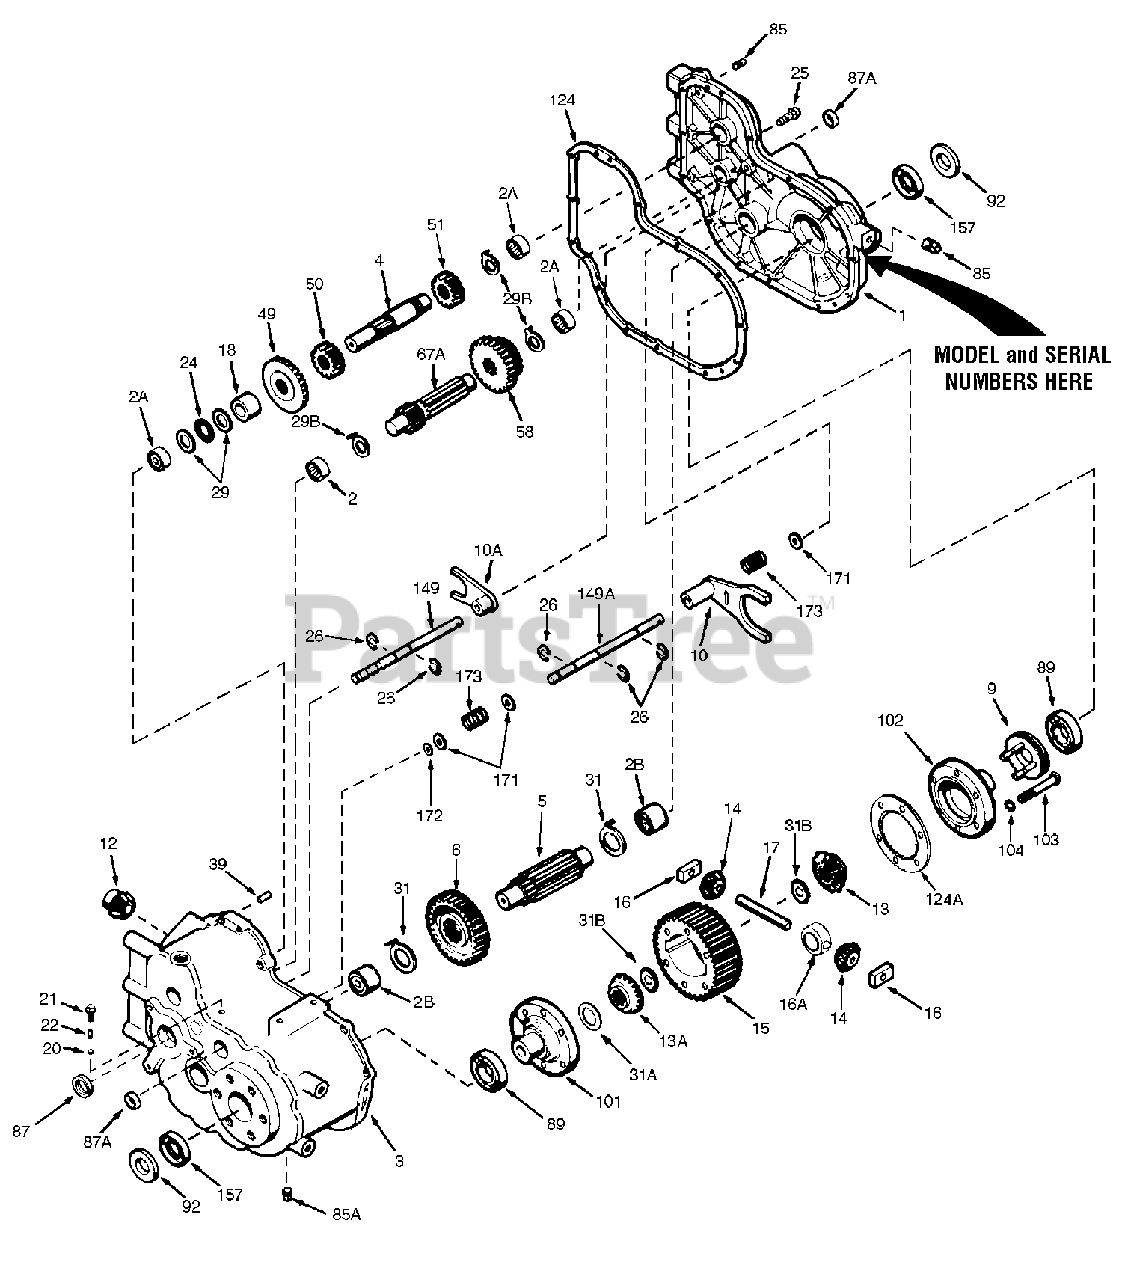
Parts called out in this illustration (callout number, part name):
1	Transaxle Cover (Includes Ref. Nos. 2A & 2B)
2	Needle Bearing 1 ID
2A	Needle Bearing
2B	Needle Bearing
3	Transaxle Case (Includes Ref. Nos. 2, 2A & 2B)
4	Countershaft
5	Output Pinion
6	Output Gear (37 teeth)
9	SHIFT COLLAR ASSEMBLY
10	Shift Fork (Diff-Lock)
10A	Shift Fork
12	Bevel Pinion(13 teeth-steel)(Ship Loose Part)
13	Bevel Gear (16 teeth-steel)
13A	Bevel Gear (16 teeth-steel)
14	Bevel Pinion (10 teeth-steel)
15	Ring Gear
16	Drive Block
16A	Spacer Block
17	Drive Pin
18	Spacer
20	Ball, 3/16 dia.
21	CAPSCREW, 1/4-20 x 5/8
22	Detent Spring
24	Thrust Bearing
25	CAPSCREW, 5/16-18 x 1
26	Retaining Ring
29	Washer
29B	Washer
31	Washer
31A	Washer
31B	Belleville Washer
39	Dowel Pin
49	Bevel Gear (30 teeth)
50	Spur Gear (16 teeth)
51	Spur Gear (20 teeth)
58	Shifter Gear (23 & 27 teeth)
67A	Shifter & Brake Shaft (13 teeth)
85	Plug, 1/8-27
85A	Magnetic Drain Plug, 3/8-18
87	Oil Seal 1
87A	Oil Seal, 1/2
89	Ball Bearing
92	Spacer (Ship Loose Part)
101	Differential Carrier (Includes Ref. No 31A)
102	Differential Carrier
103	CAPSCREW, 3/8-16 x 2-3/4
104	Lockwasher, 3/8
124	Gasket
124A	Shim
149	Shift Rod (High-Low)
149A	Shift Rod (Diff-Lock)
157	Oil Seal 1-1/8
171	Thrust Washer .502 ID
172	Retaining Ring
173	Spring (Diff-Lock)
